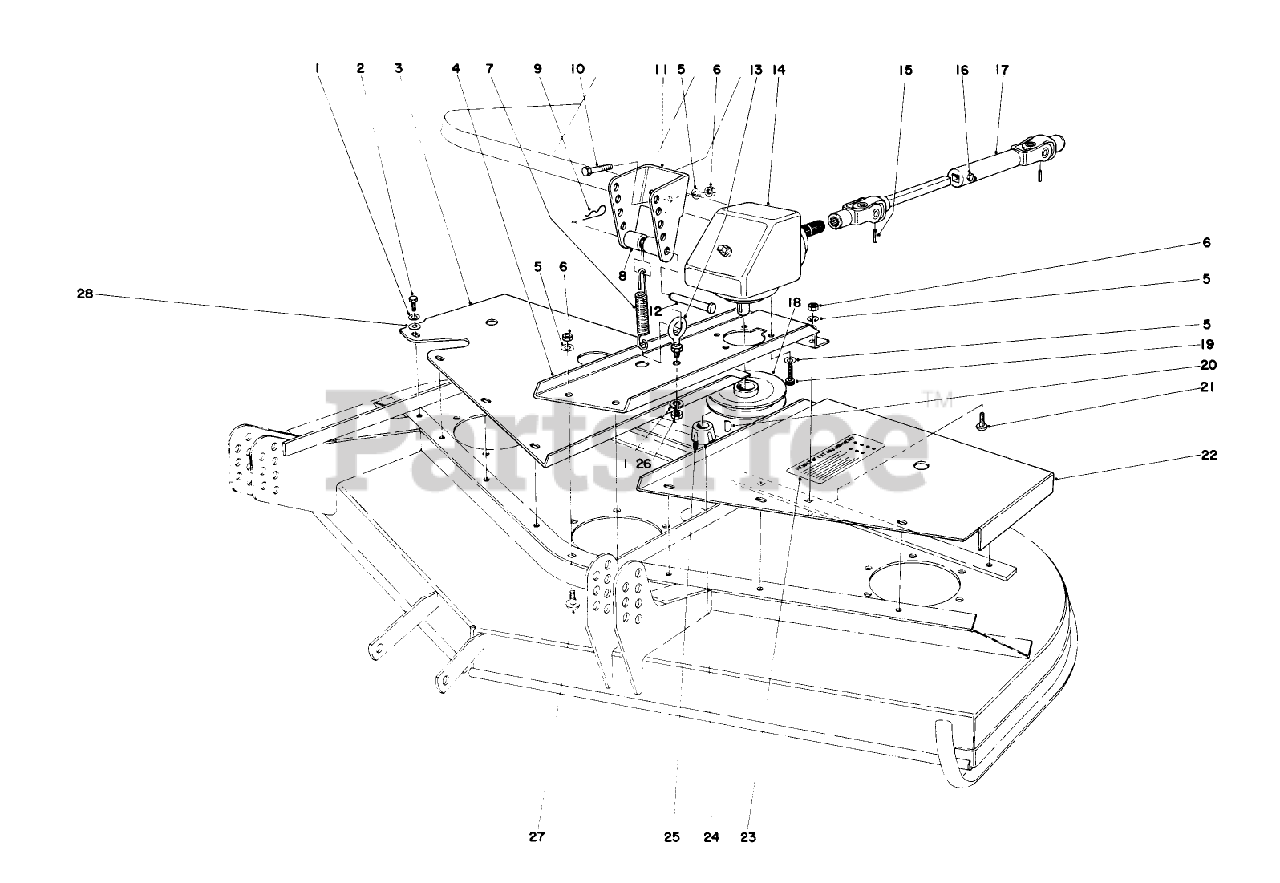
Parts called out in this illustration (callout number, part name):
4	GASKET
5	GASKET
10	SEE SB GEN#14-01
17	SEE SB GEN 14-01
18	SEE SB GEN#14-01
19	SEE SB GEN#14-01
